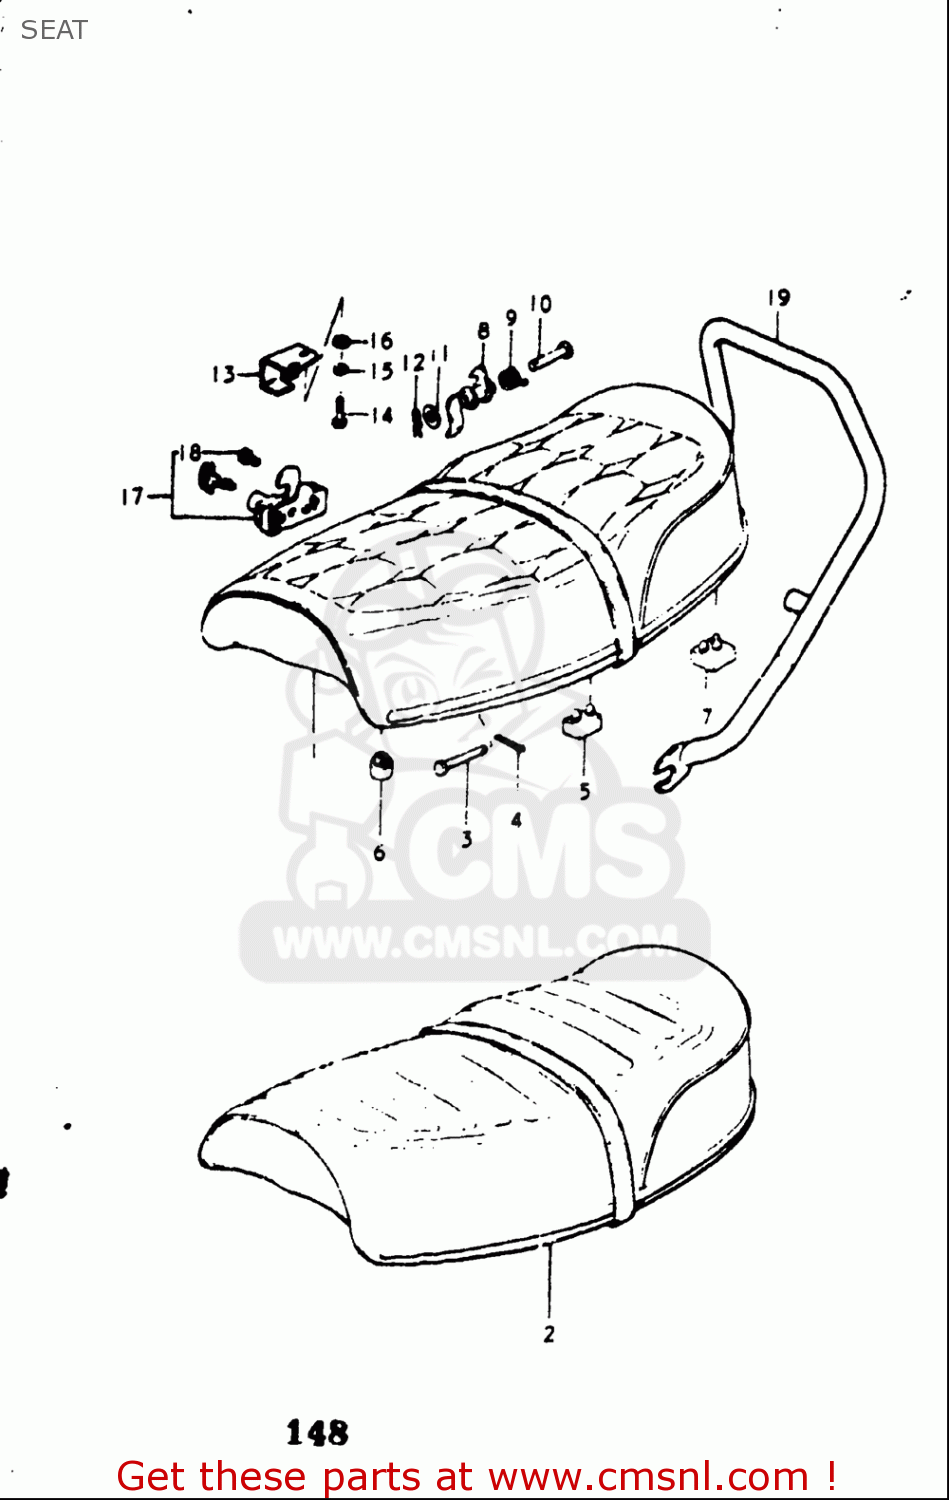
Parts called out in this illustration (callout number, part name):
1	SEAT ASSY
2	SEAT ASSY
3	PIN
4	PIN
5	CUSHION
6	CUSHION(11.5X22X20)
9	SPRING
10	PIN
11	WASHER
12	CLIP
13	PLATE,SEAT CLAMP GUIDE
14	BOLT
15	WASHER,LOCK
16	WASHER
17	LOCK SET,HELMET
